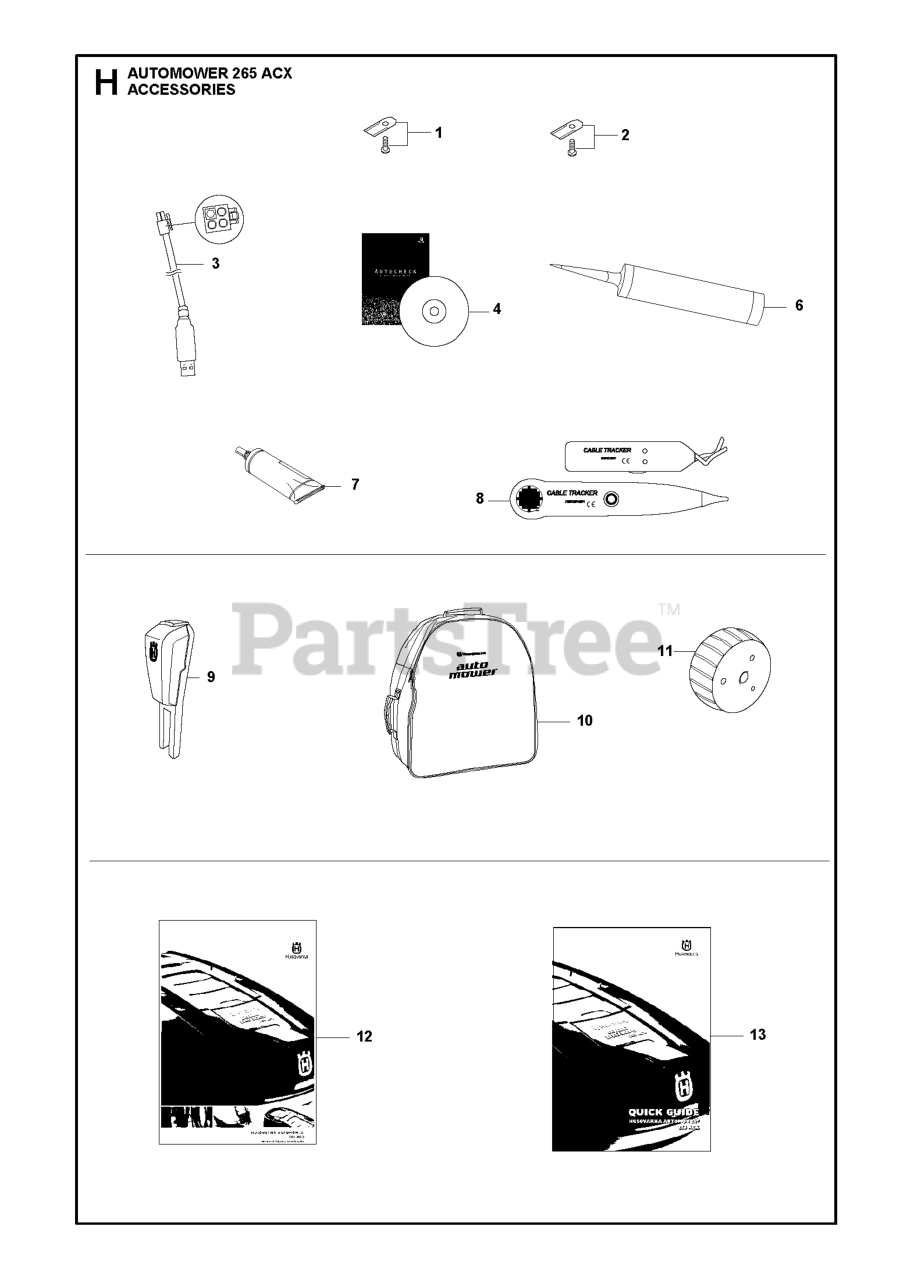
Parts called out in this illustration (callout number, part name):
1	BLADE - BULK PACK 500 PCS
1	BLADE 45PCS, CARBON
1	HUS 9 PC BLADE SET .35MM
1	BLADE KIT
2	BLADE 9 PCS EXTRA THICK
2	BLADE 300PCS -SINGLE HOLE THIC
2	BLADE
2	BLADE BLADE KIT INCL PACKAGING
3	USB SERVICE CABLE
7	SEALANT
8	TEST EQUIPMENT
9	SIGNAL BOOSTER
11	WHEEL ASSY
11	HEAVY FRONT WHEEL KIT INCL PAC
